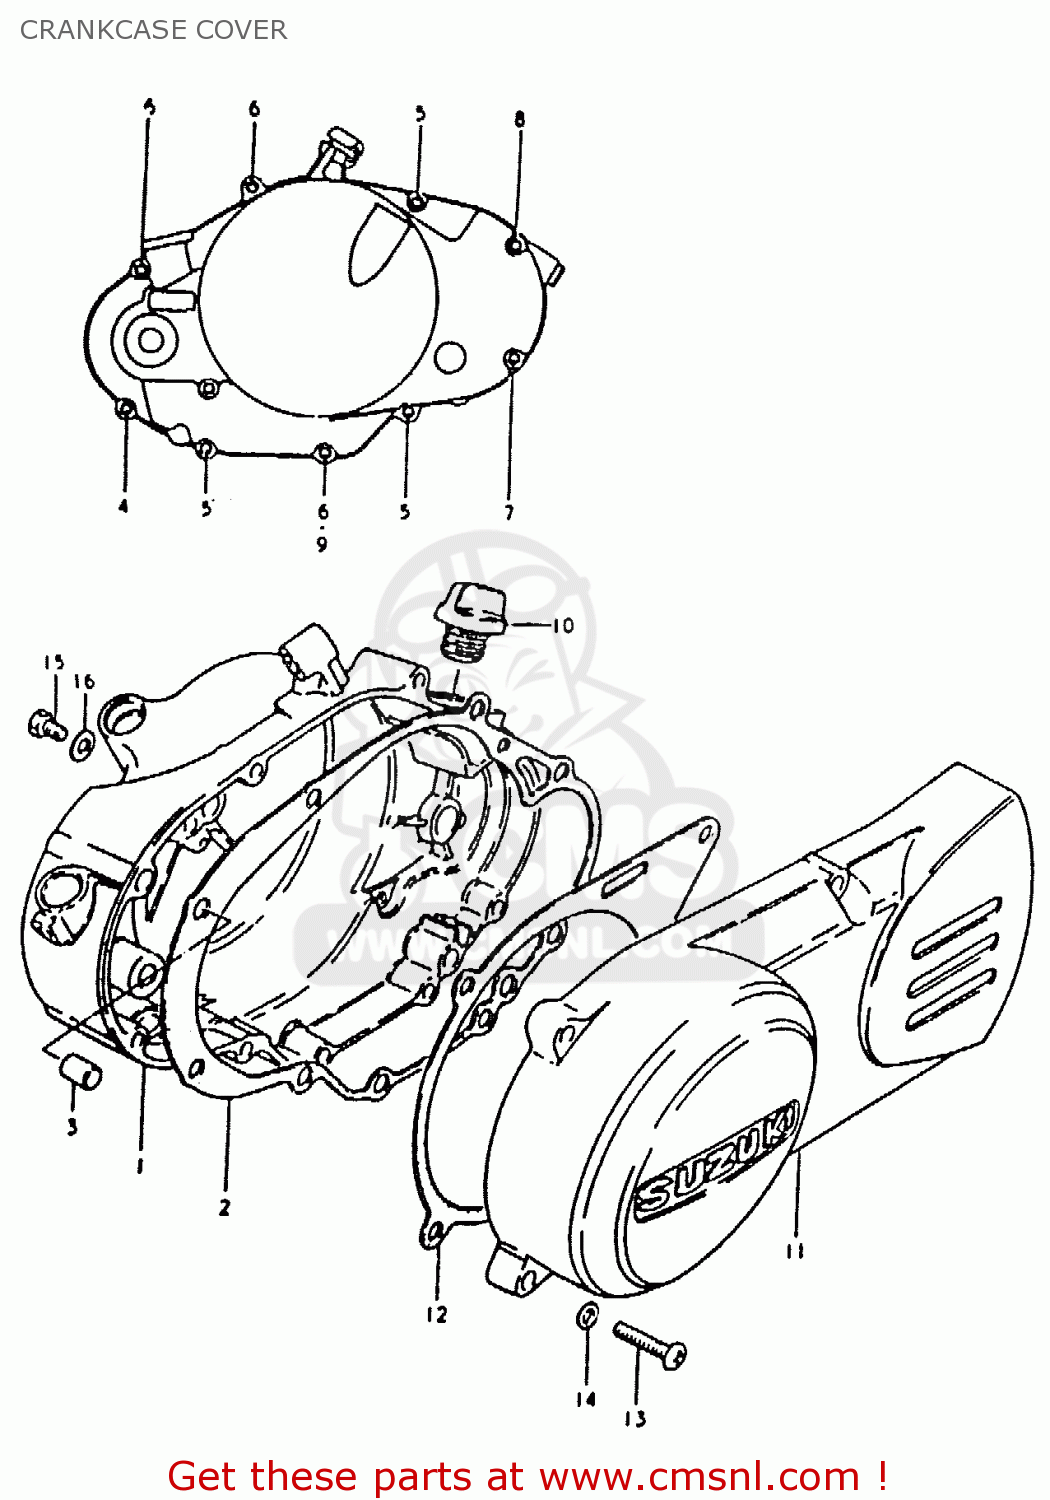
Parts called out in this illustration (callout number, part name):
1	COVER SET,CLUTCH
2	GASKET,CLUTCH COVER (MCA)
3	PIN
4	SCREW
5	SCREW 6X30
6	SCREW
7	SCREW
8	SCREW 6X60
9	GASKET(6.2X11X1).2 (NAS)
10	PLUG
11	COVER,MAGNETO
12	GASKET,MAGNETO COVER (NAS)
13	SCREW
14	WASHER
15	SCREW(6X10)
16	GASKET(6.2X11X1) (NAS)
